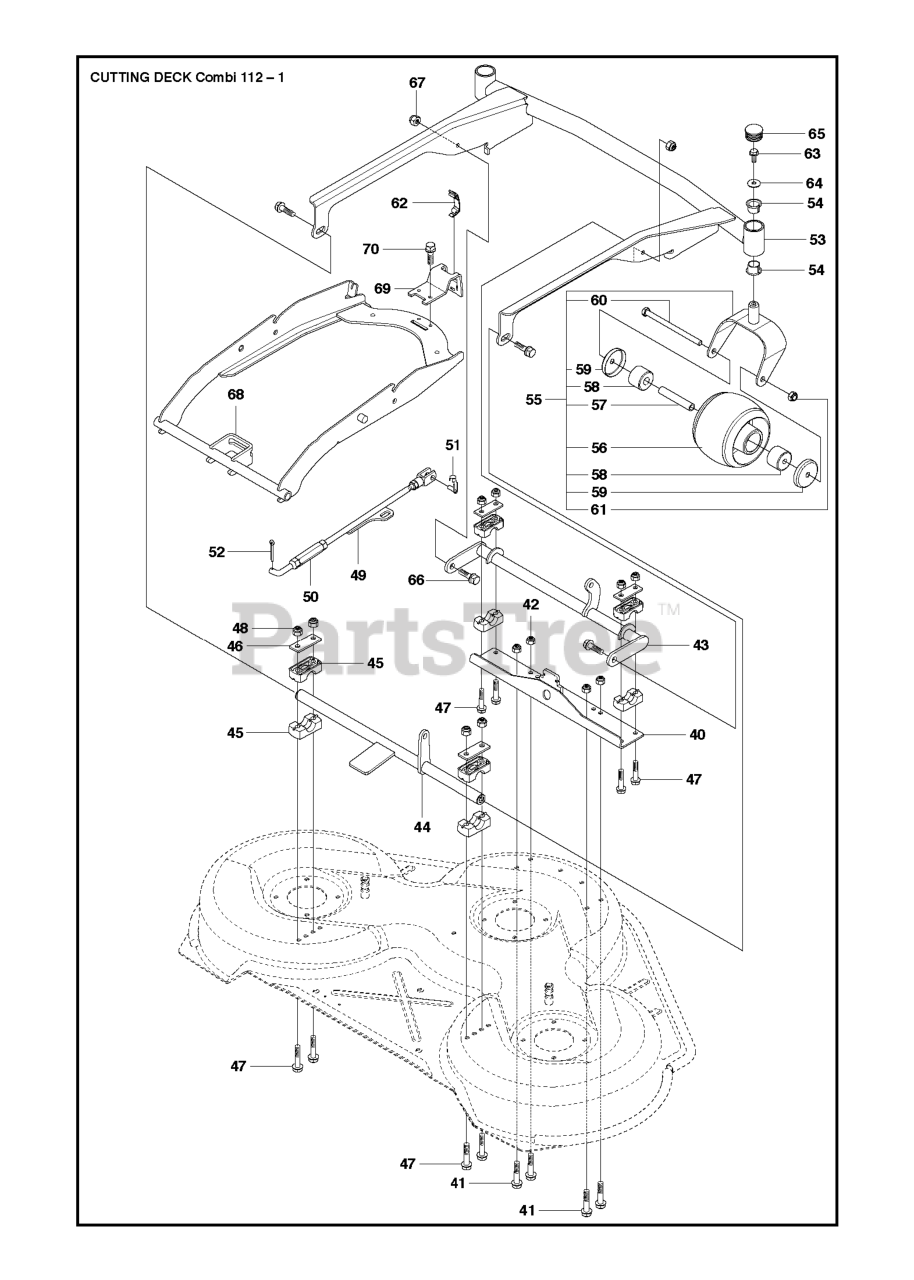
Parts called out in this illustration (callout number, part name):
42	LOCKNUT M8
48	LOCKNUT M8
49	PARALLELL ROD ASSY
50	PARALLEL ROD
53	DECK FRAME
55	Pivots
61	NUT
67	LOCKNUT M8
68	DECK ATTACHMENT
70	SCREW
